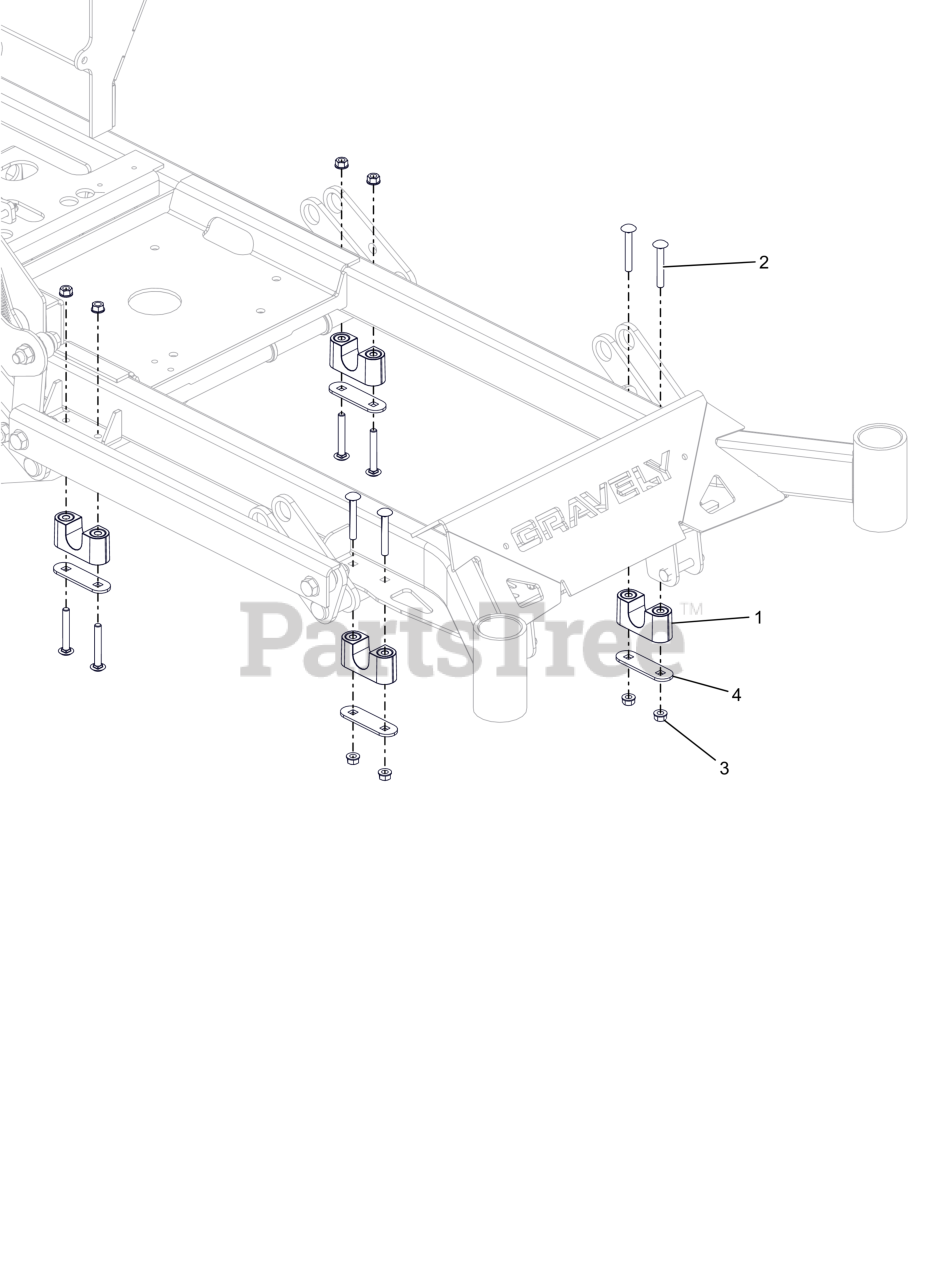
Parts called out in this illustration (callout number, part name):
1	ASM-BUSHING, DECK LIFT
2	BLT, RHSSN.31-18X2.25 G5 ZCC
3	NUT,LK-CTR-FLG .31-18 GF ZCC
4	PLATE, BEARING SUPPORT
